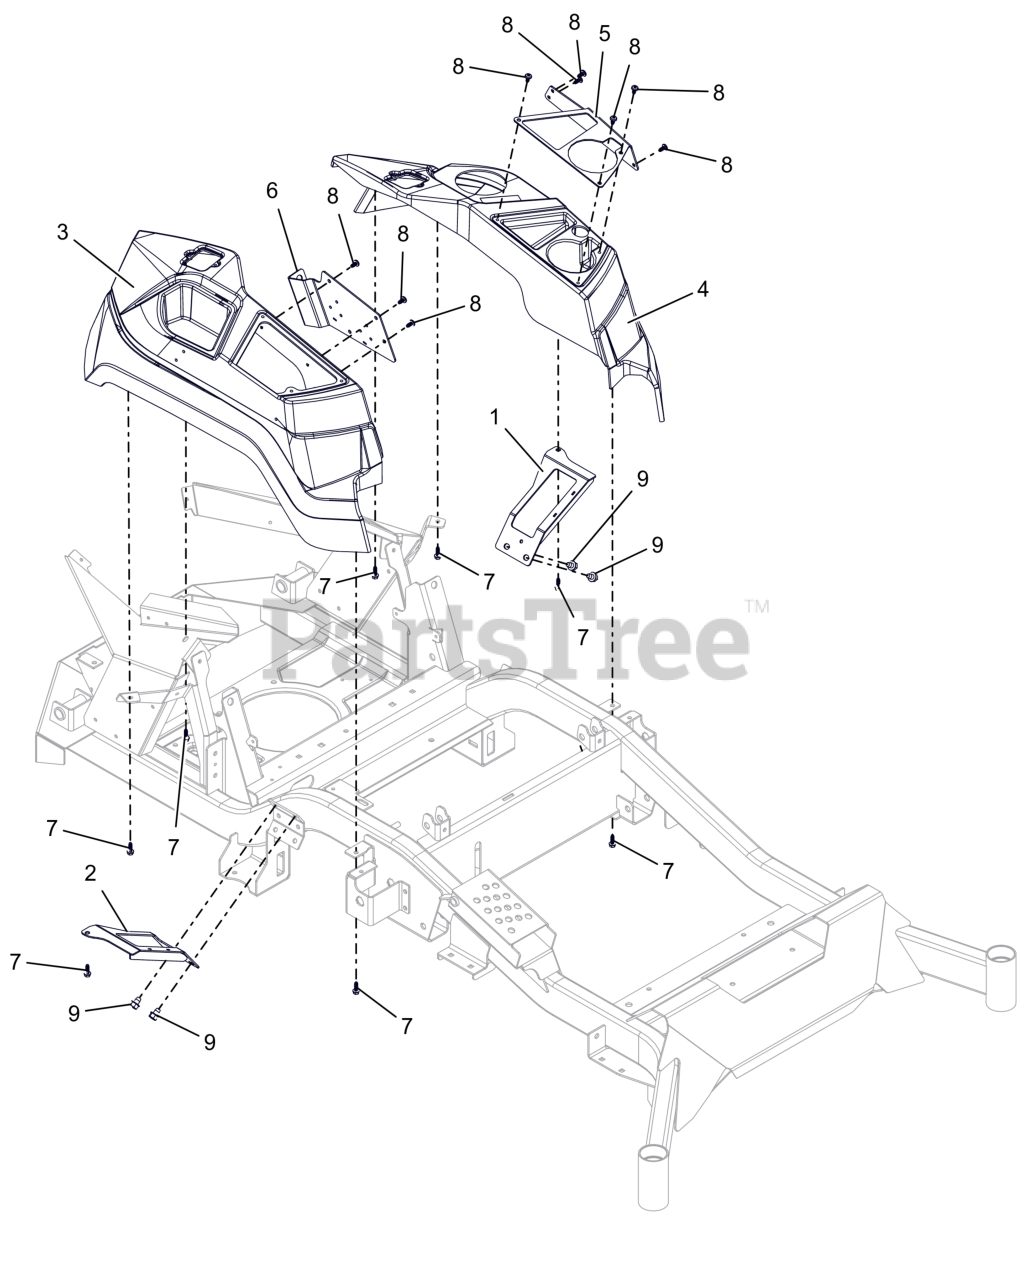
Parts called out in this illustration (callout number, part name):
1	WLDMT, LH FENDER MOUNT
2	WLDMT, RH FENDER MOUNT
3	FENDER, RH APEX - 2017
4	FENDER, LH APEX
5	PLATE, APEX CUP HOLDER COVER
6	BRKT, FENDER/RELAY MOUNTING
7	SCR, PLASTITE .25-10X.75 ZCC
8	SCR-PAN .25-15X.50 6L H/LZB500
9	SCR,TAP .375-16X.50 HWH TR ZCC
